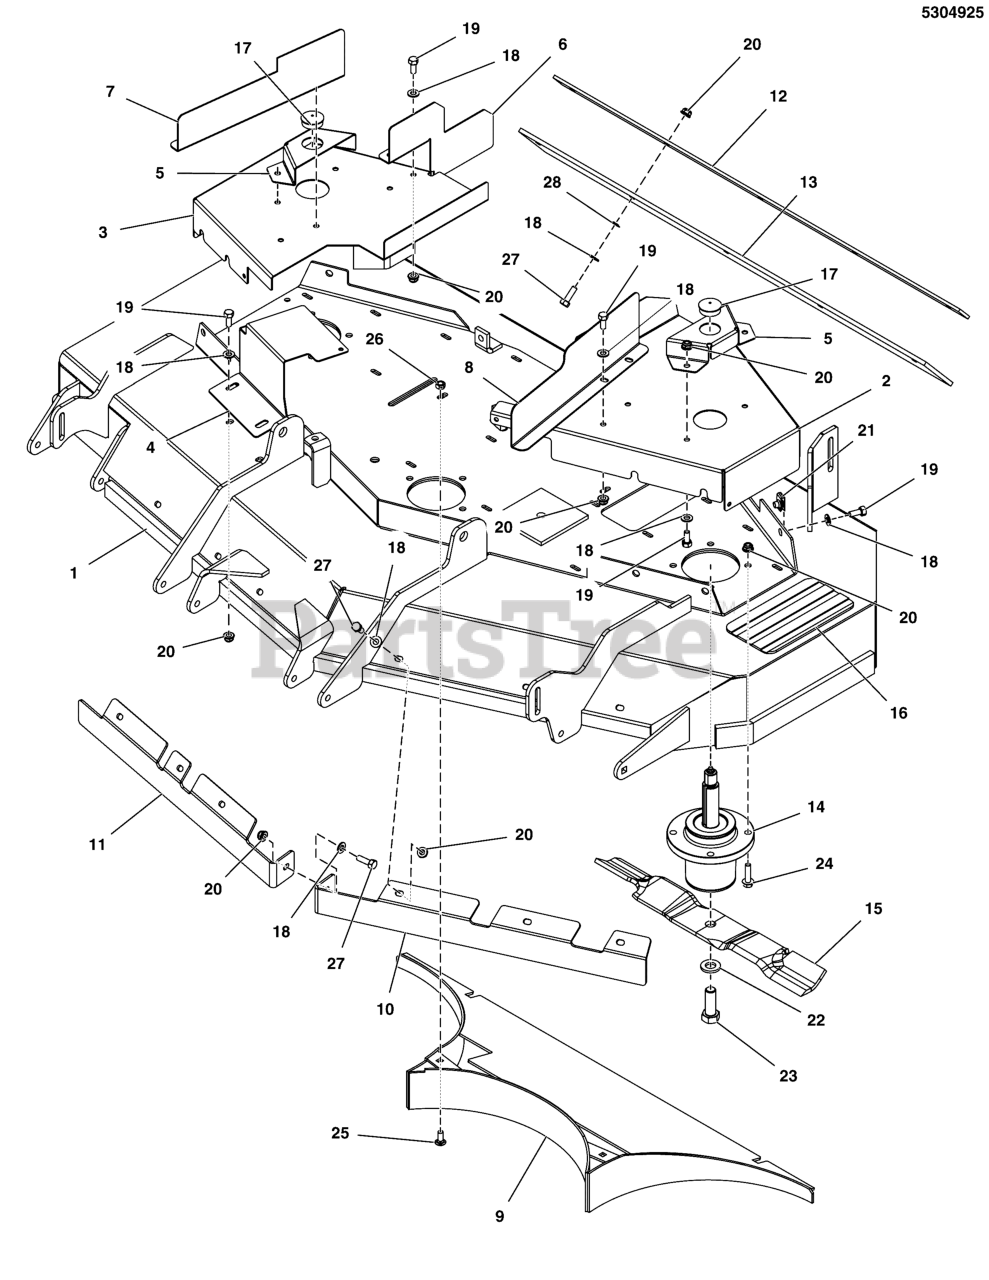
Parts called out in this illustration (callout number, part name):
1	DECK SHELL W/DECALS, 2100 52RDCE (5416061B)
2	PLATE, DECK GUARD, LH 52" CE - RED
3	PLATE, DECK GUARD, RH 52" CE - RED
4	GUARD, FRONT CUTTER DECK, 52" CE - RED
5	GUARD, GREASE FITTING, CE - RED
6	PLATE, DECK SHIELD, REAR, 52, RH - RED
7	PLATE, DECK SHIELD, FRONT, 52, RH - RED
8	PLATE, DECK SHIELD, FRONT, 52, LH - RED
9	WELD, REAR BAFFLE, SHRT - BLK
10	BAFFLE, FRONT DISCHARGE LH - RED
11	BAFFLE, FRONT DISCHARGE RH - RED
12	PLATE, FLAP RETAINER, 2000 RD - BLK
13	FLAP, 2000 REAR DISCHARGE
14	SPINDLE ASSM, ALUMINUM, LONG SHAFT
15	BLADE SET, MULCH, 52 DECK (SET OF 3)
16	SAFETY WALK, 4.00 X 7.50
17	PLUG, PANEL, 1.25 - BLACK
18	WASHER, 5/16" SAE
19	BOLT, 5/16-18 X 3/4 GD5
20	NUT, 5/16-18 HEX NYLOCK FLANGE NUT
21	BODY CLIP, 5/16-18-7GA MATERIAL
22	WASHER, BLADE BOLT, 9/16" F436, CZ
23	BOLT, 5/8-11 X 1-3/4 GD8
24	BOLT, Flange Head, 5/16-18 x 1-1/4
25	BOLT, 5/16-18 X 3/4, CARRIAGE, GD5, CZ
26	NUT, 5/16-1/8, HEX, CNTR LK, ZINC PHOS/OIL
27	BOLT, 5/16-18 X 1" GRD5 YZ
28	5/16" PUSH-ON NUT RETAINER, STL, CZ
